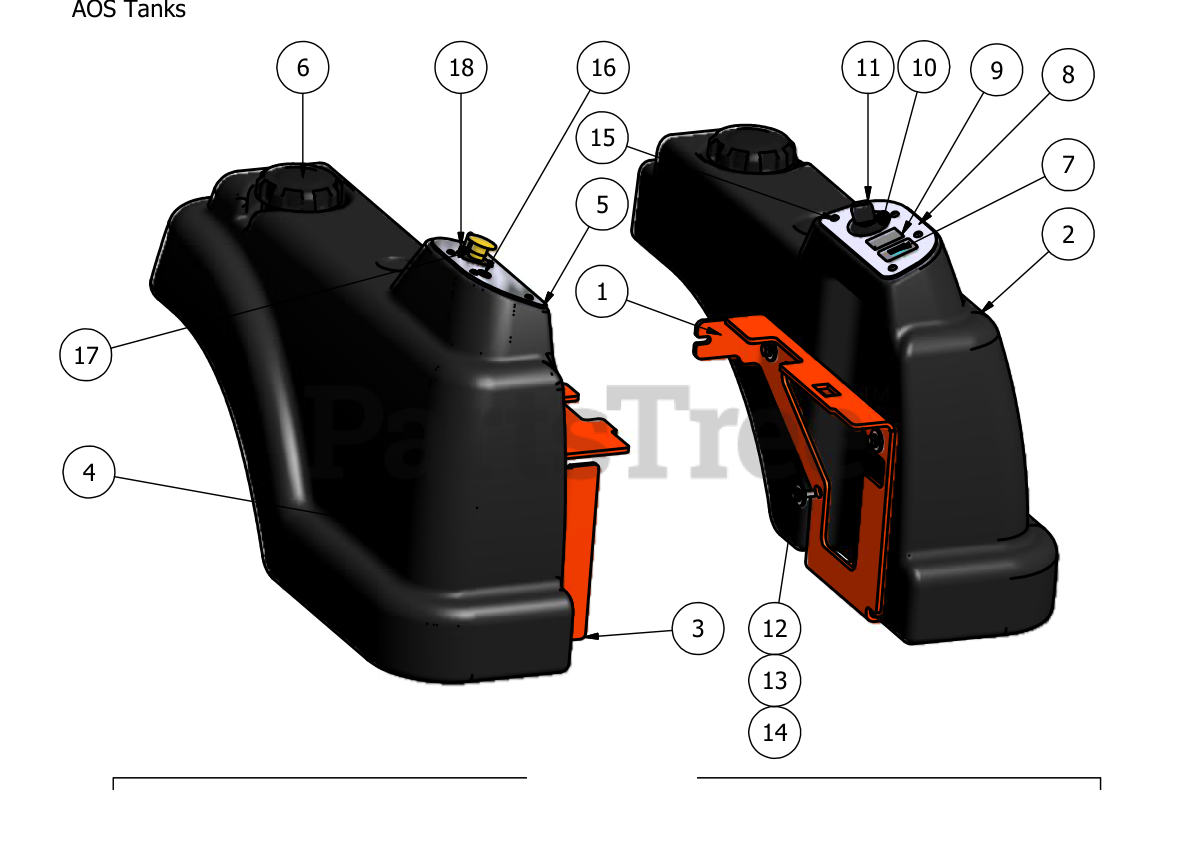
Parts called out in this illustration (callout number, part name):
1	Left Fuel Tank Swing Support
2	Left Fuel Tank with Fender
3	Fuel Tank Support (Right)
4	Right Fuel Tank with Fender
5	AOS control panel (Right)
7	Tachometer
8	Control Panel (Left)
9	control panel stop
10	Ignition Switch
11	Ignition Key
12	5/16" x 1" Hex Bolt
13	5/16" Lock Washer
14	.505 Nylon Spacer
15	10mm x 32 x 1" Bolt
17	PTO Engager
18	Deck Lift Joystick
